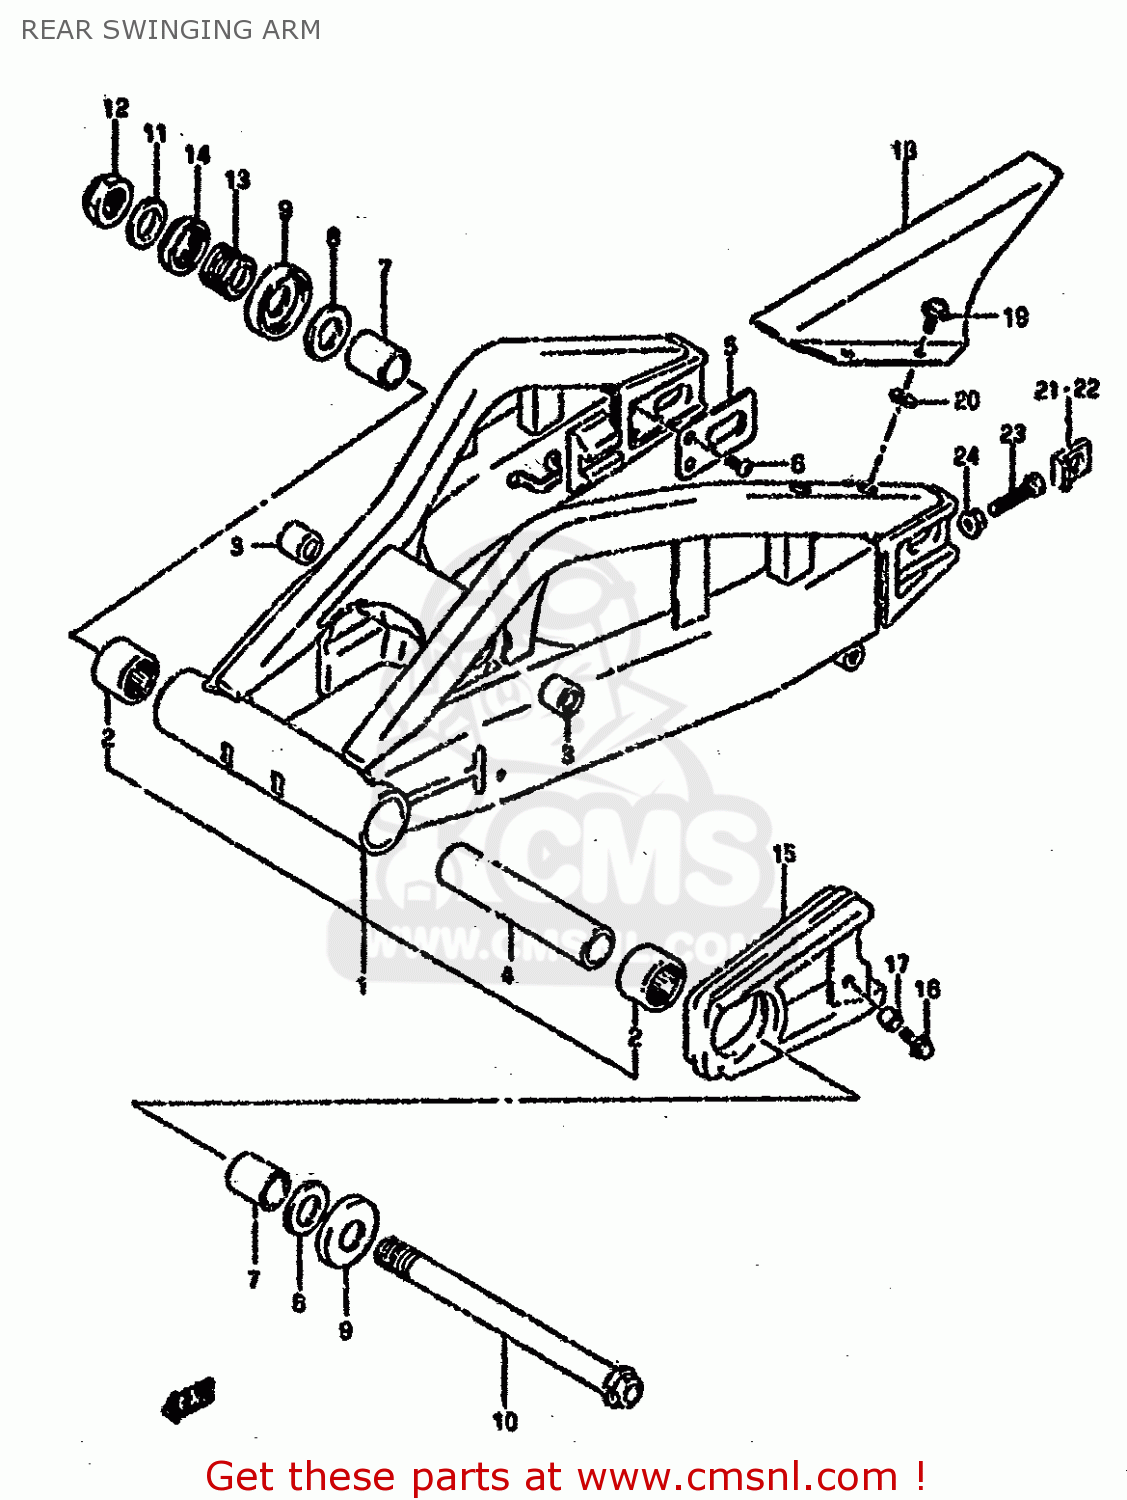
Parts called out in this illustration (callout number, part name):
1	SWING ARM ASSEMBLY,REAR
2	BEARING(30X40X25)
3	BEARING(17X24X20)
4	SPACER (25.4X31.8X157.9)
5	PLATE,RR SWING ARM BRKT
6	SCREW 6X10
7	SPACER,REAR SWING ARM PIVOT
8	WASHER
9	DUST SEAL,RR SWGARM PIVOT
10	SHAFT,REAR SWING ARM PIVOT
11	WASHER(25.2X42X3.2)
12	NUT
13	BOLT,REAR SWING ARM PIVOT
14	NUT,REAR SWING ARM PIVOT BOLT
15	BUFFER,CHAIN TOUCH DEFENSE
16	BOLT 6X20,WITH PLAIN WASHER
17	SPACER
18	CASE,CHAIN
19	SCREW(6X20)
20	WASHER
21	WASHER,CHAIN ADJUSTER
22	WASHER,CHAIN ADJUSTER
23	BOLT(8X50)
24	NUT
